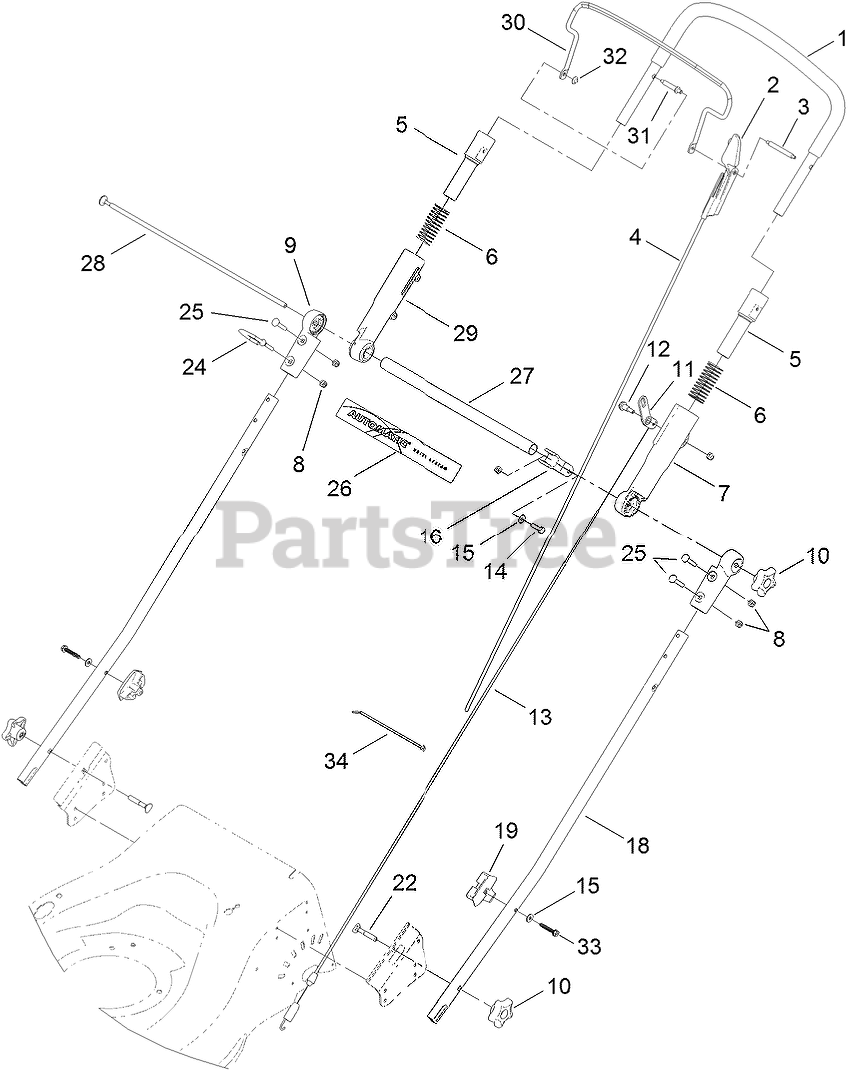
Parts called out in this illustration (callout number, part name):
1	UPPER HANDLE ASM
2	STOP-PIVOT
3	PIN-BAIL, LH
4	CABLE-BRAKE
5	SLEEVE-INNER
6	SPRING-COMPRESSION
7	SLEEVE-OUTER, LH
8	NUT-LOCK, NI
9	MOUNT-HANDLE, LOWER
10	KNOB-HANDLE
11	LEVER-TRACTION
12	BOLT-SHOULDER
13	CABLE-TRACTION
14	SCREW-HH
15	WASHER-FLAT
16	CLAMP-CABLE
18	TUBE-HANDLE
19	ANCHOR-BAG
22	SCREW-HANDLE
24	GUIDE-ROPE, UPPER
25	SCREW-CARR
26	DECAL-ADS
27	TUBE-CROSS
28	ROD-THREADED
29	SLEEVE-OUTER, RH
30	BAIL-BRAKE
31	PIN-HANDLE
32	RETAINER-PUSH ON
33	SCREW-PLASTITE
34	TIE-CABLE
